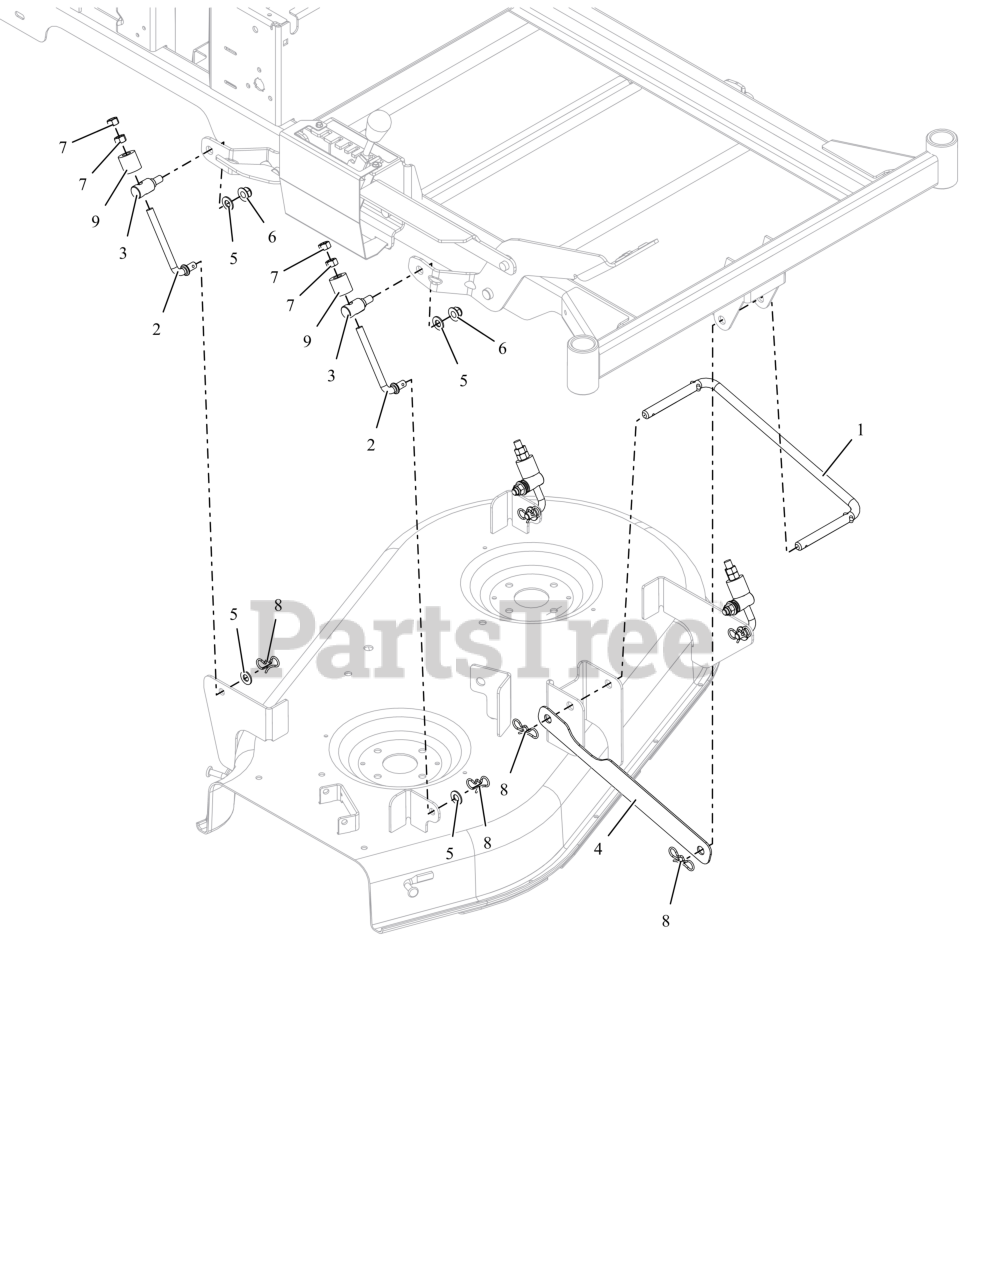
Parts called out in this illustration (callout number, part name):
1	WIREFORM, DRAG LINK
2	WIREFORM, DECK ADJUSTMENT
3	TRUNNION, DECK ADJUSTER
4	STRAP, DRAG LINK
5	WSHR,FLT .406X.812X.065 ZCC
6	NUT,NYL-FLG .38-16 GF ZCC
7	NUT-STD .375-16 G2 ZCC
8	PIN, BOWTIE .091X1.875 ZCC
9	BSHG-SLV .391X.688X.52 PM
